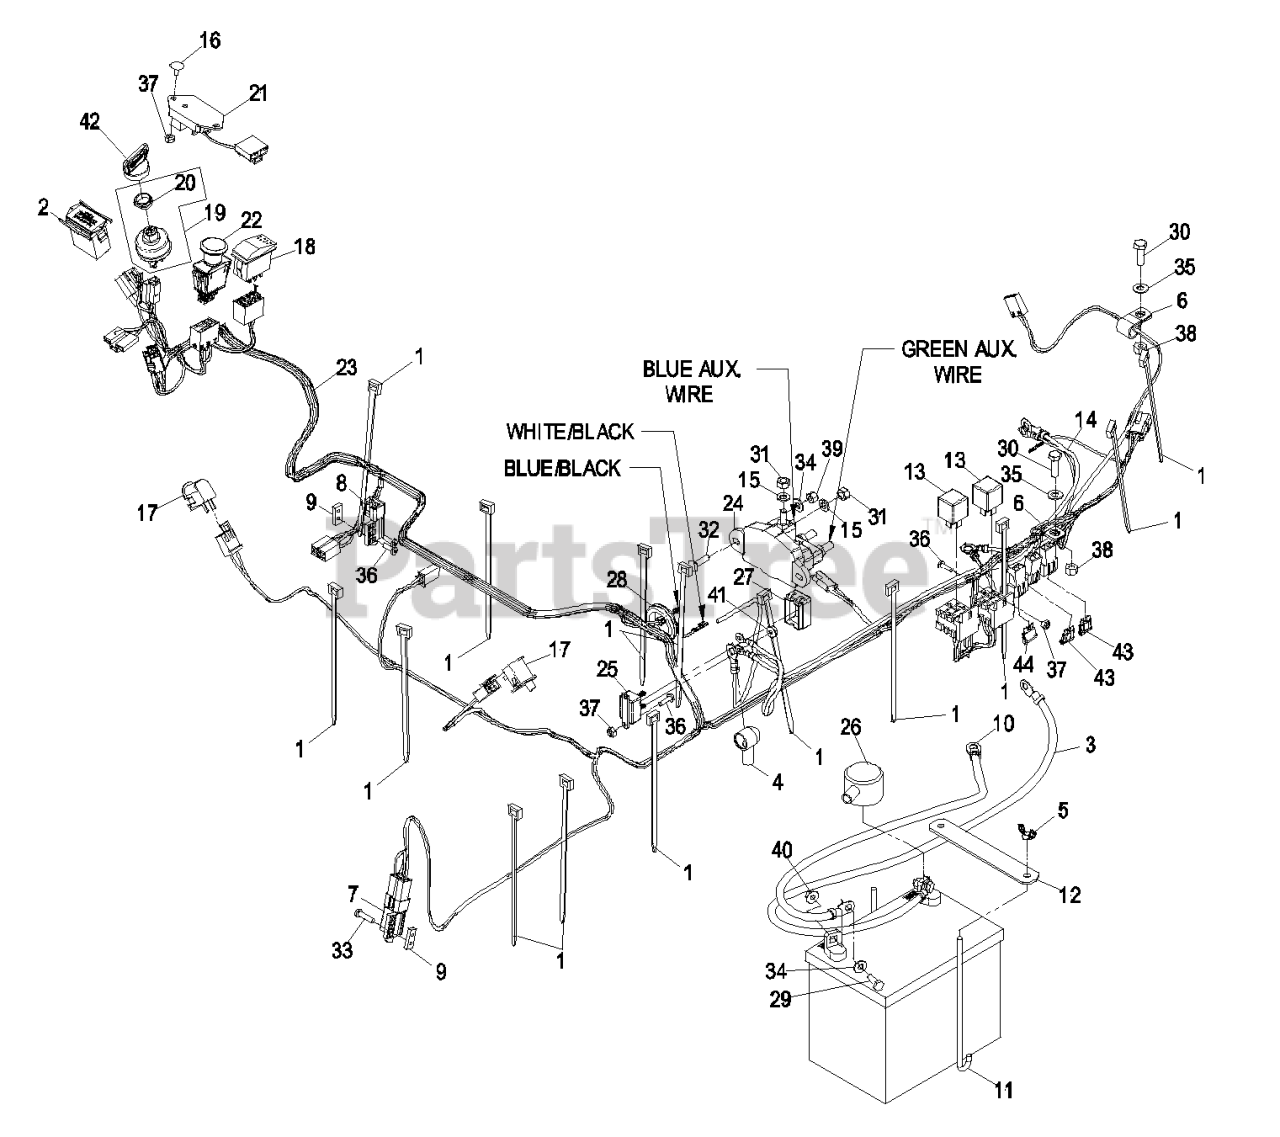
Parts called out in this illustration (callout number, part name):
1	TIE-PLASTIC
2	METER-HOUR
3	ASM,POSITIVE BATTERY CABL
4	INSULATOR-SOLENOID
5	WINGNUT
6	CLIP-LOOM
7	SWITCH-BRAKE
9	PLATE-TAPPED
10	WIRE-GROUND
11	BOLT-HOLDDOWN
12	STRAP-HOLDDOWN, BATTERY
13	RELAY
14	HARNESS,AUX HYDRAULICS
15	WASHER-LOCK
16	BOLT-CARR
17	SWITCH-BAIL
18	SWITCH,ROCKER (ON)-NONE-(
19	ASM,SWITCH W/NUT
20	NUT-SWITCH, IGNITION
21	MODULE-DELAY, SEAT
22	SWITCH-PTO
23	HARNESS,WIRING FMZ KOHLER
24	CONTACTOR, REVERSING POLA
25	CIRCUIT BREAKER,40A
26	INSULATOR-BATTERY
27	COVER,CIRCUIT BREAKER
28	GROMMET-RUBBER
29	SCREW-HH
30	SCREW-HH
31	NUT-HEX
32	SCREW-CARR
33	SCREW-PPH
34	WASHER-FLAT
35	WASHER-PLAIN
36	SCREW-PPH
37	NUT-LOCK, NI
38	NUT-LOCK, NI
39	NUT-LOCK, NI
41	NUT-KEPS
42	KEY-IGNITION
43	FUSE-BLADE TYPE, 20 AMP
44	FUSE-BLADE, 15 AMP
